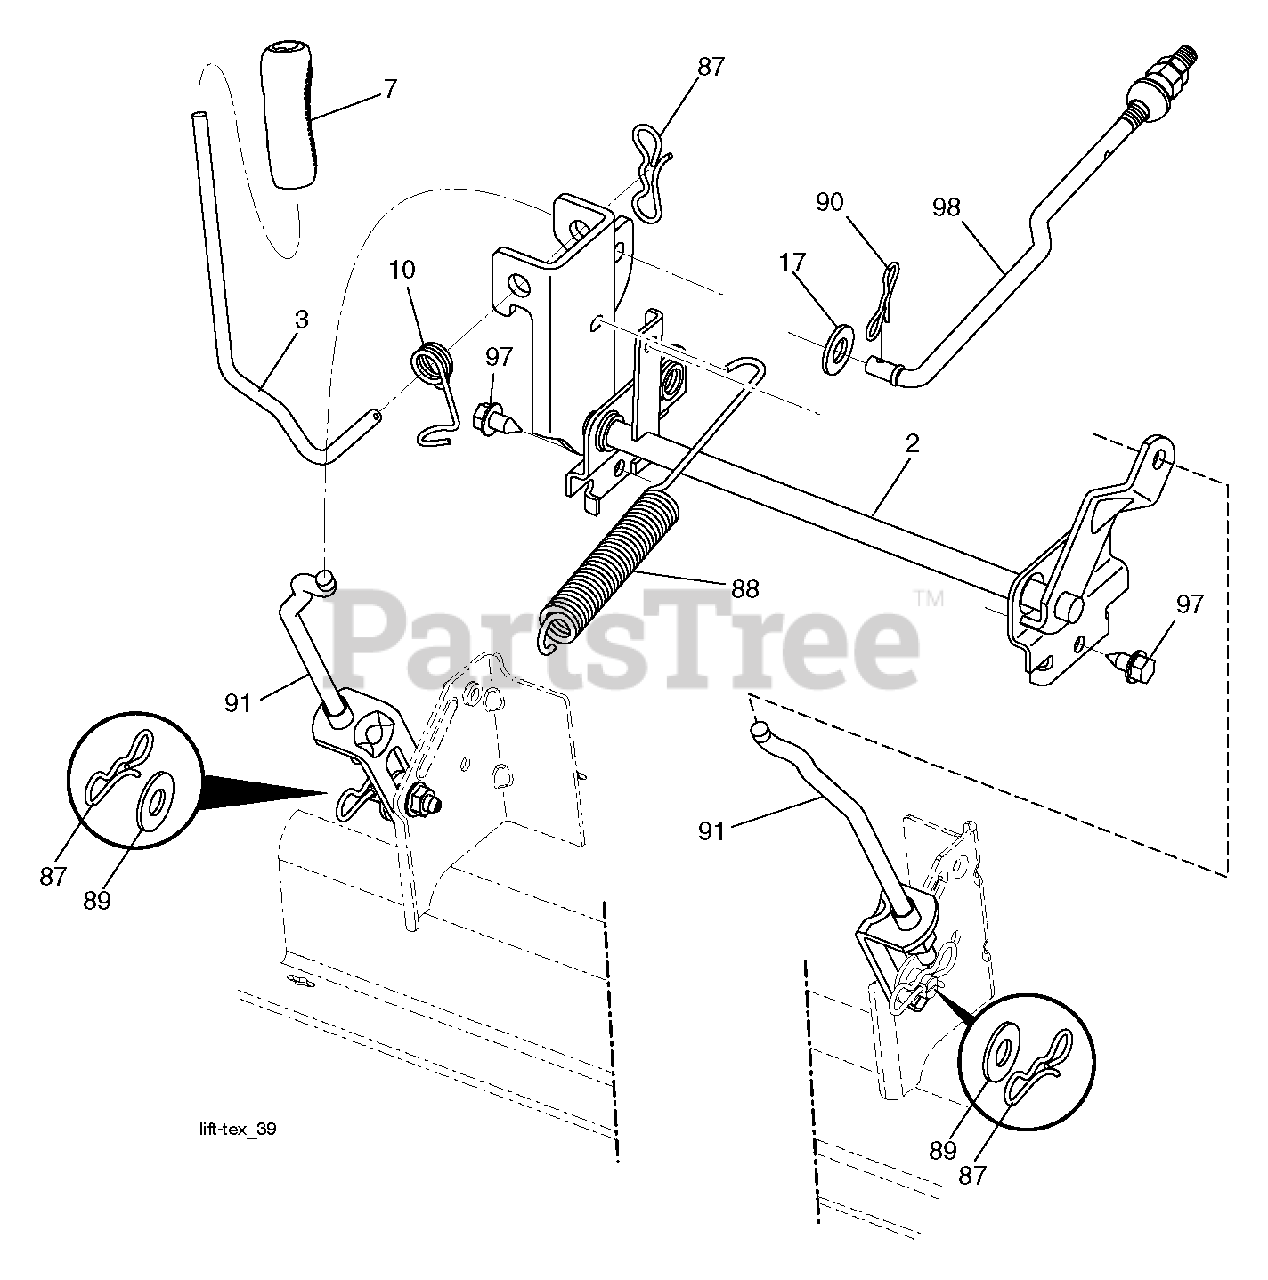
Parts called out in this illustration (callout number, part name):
2	SHAFT.ASM.CROSS.LIFT
3	LEVER.LIFT.HANDLE.LT
7	GRIP.HANDLE.LIFT.PVC.BLACK
10	SPRING.TORSION.LIFT.HANDLE
17	WASHER
87	PIN.COTTER.7/16.BOW TI.
88	SPRING.LIFT.ASSIST
89	WASHER.CLEAR.ZINC
90	PIN.COTTER.5/16.BOW TI
91	LINK.ASM.LIFT.REAR
97	SCREW, 3/8-16X3/4
98	LINK.ASM.SUSP.FRONT.MW
